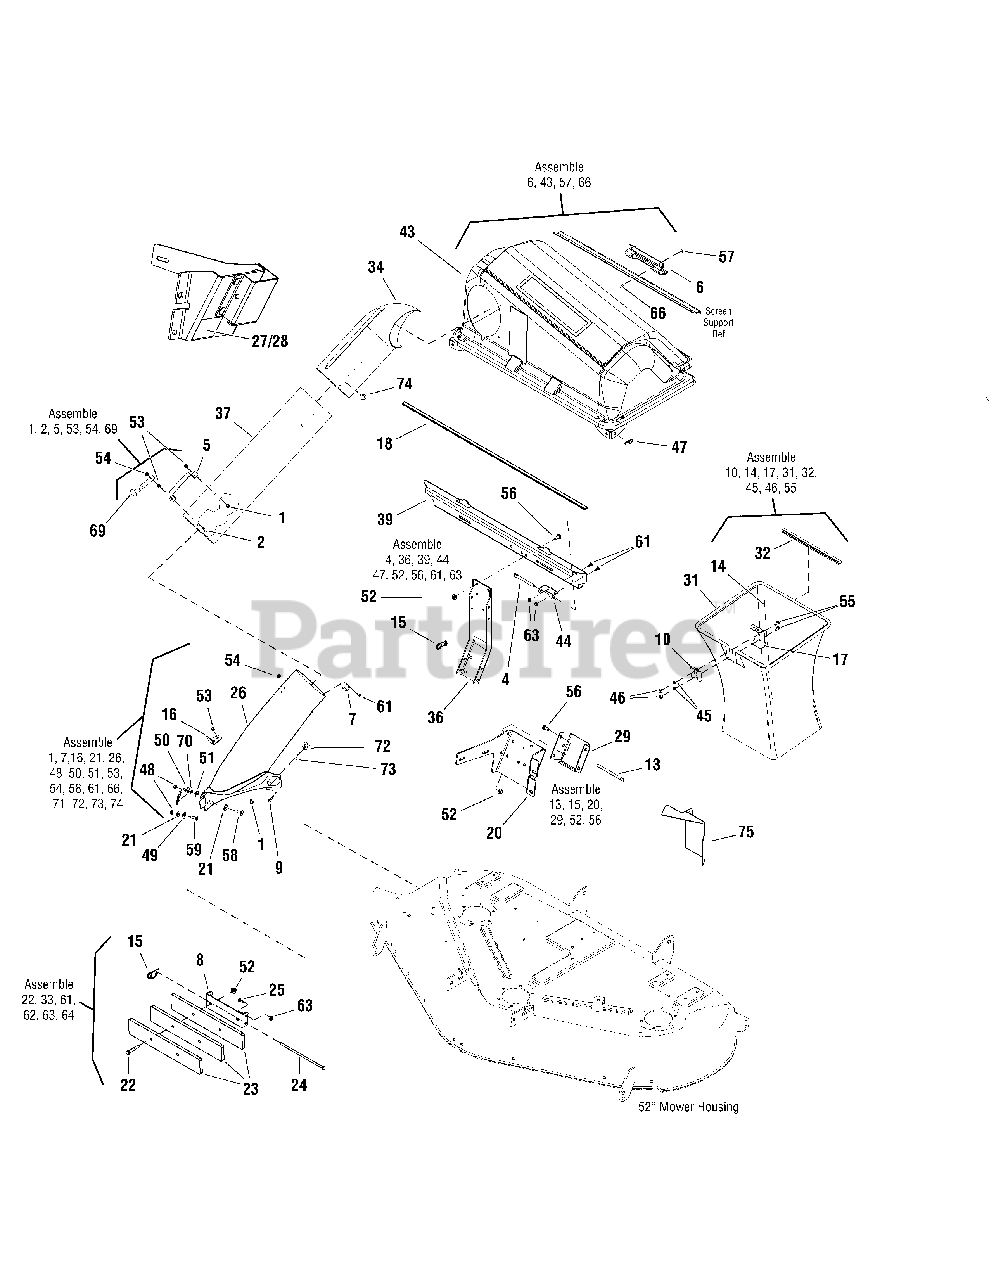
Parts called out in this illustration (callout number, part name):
1	SCREW, Truss-Head, 1/4-20 x 1/2"
2	SCREW, Truss-Head, 1/4-20 x 1"
4	PIN, Cover Hinge
5	HANDLE CONNECT, Tube
6	HNADLE, Plastic
7	PIN, Latch
8	BRACKET, Front Weight Mount
9	BOLT, Carriage, 1/4-20 x 3/4"
10	CLAMP, 1/2" Diameter Rod
13	PIN, Hinge
14	BAG, Grass 15.9 X 16.5
15	RETAINER, Spring
16	UPSTOP, Deflector
17	HANGER, Grass Bag
18	TRIM, 31-1/2"
20	HITCH, Bagger
21	WASHER, 5/16, 1-1/4 OD
22	CAPSCREW, Hex-Head, 3/8-16 x 2-1/4"
23	WEIGHT, Counter
24	ROD, Seat Hinge
25	BOLT, Shoulder, .250X.312 .25
26	BOOT, Bagging, 46/52 Mower
27	MYLAR OVERLAY, ID Sticker
28	ID STICKER
29	BRACKET, Upright Mount
31	HOOP, Twin Catcher, 1/2" Diam.
32	EDGING, 12"
34	ELBOW, Upper TubeT
36	SUPPORT, Upright
37	TUBE, Clear
39	CROSS SUPPORT, Twin
43	COVER ASSEMBLY, Twin Bagger
44	PIVOT, Hinge
45	LOCKWASHER, Spring, 5/16
46	NUT, Hex, 5/16 x 18
47	PIN, Quick
48	NUT, Hex-Flange, 5/16
52	NUT, Hex-Flange, Whiz, 3/8-16
53	NUT, Hex-Flange, 1/4-20
54	NUT, Hex-Flange, Top-Lock, 1/4-20
55	BOLT, Carriage, 5/16-18 x 3/4"
56	BOLT, Carriage, 3/8-16 x 7/8"
57	NUT, Hex-Lock, Nylon-Insert, 10-24, 1/4-20
58	BOLT, Carriage, 5/16-18 x 1, G5
59	BOLT, Carriage, 5/16-18 x 1-1/4, G5
61	BOLT, Carriage, 1/4-20 x 5/8"
63	NUT, Hex-Flange, Whiz, 1/4-20
66	SCREW, Truss-Head, Phillips, 10-24 x 3/4"
69	STRAP, HOOD, Black Rubber
70	WASHER, Wave
72	KNOB, 5-Point, 1/4-20
73	WASHER, Flat, 9/32 X 1
74	SCREW, 1/4 X 3/4
75	SHIELD, Muffler
